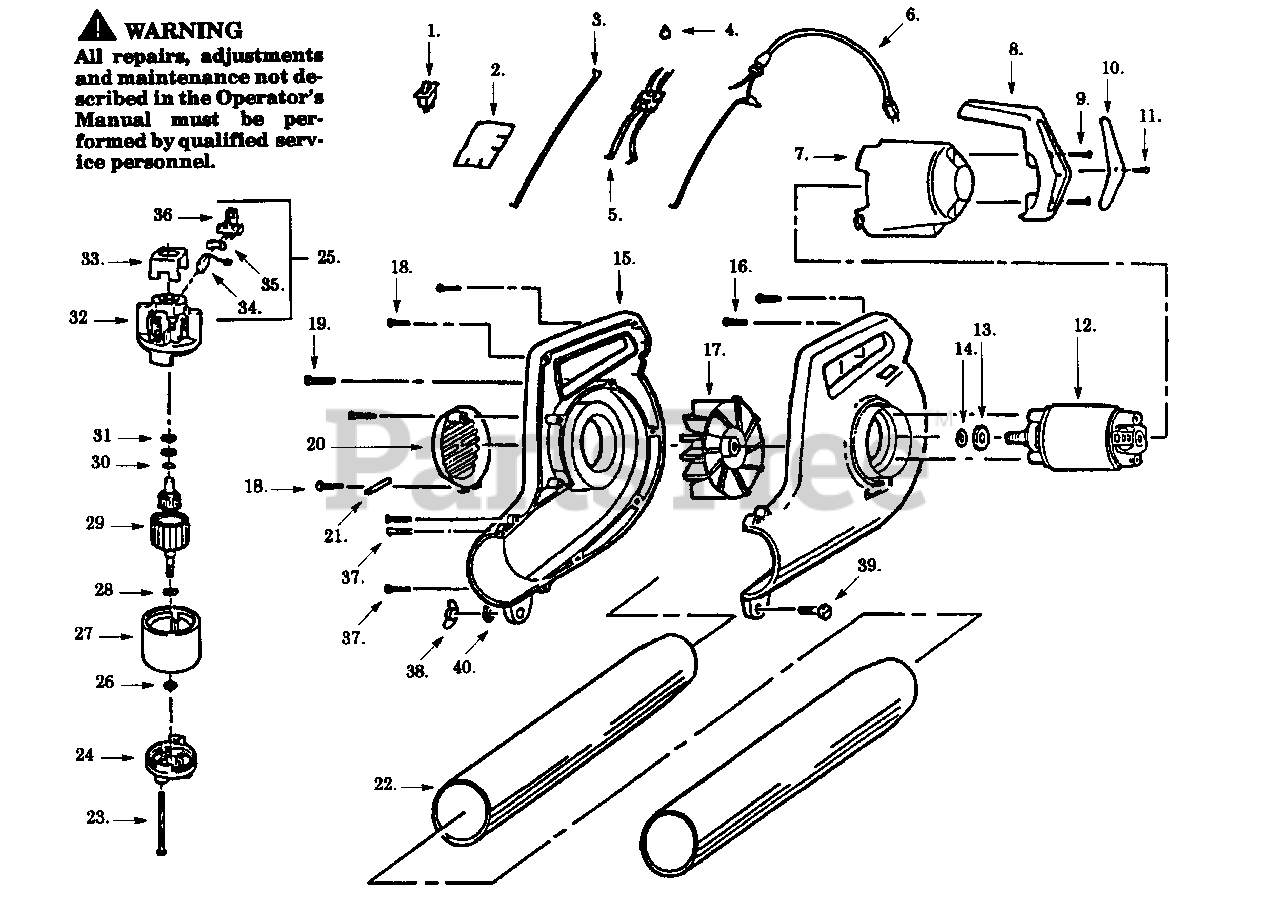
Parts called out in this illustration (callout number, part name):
1	On-Off Switch
2	Mounting Board
3	Lead Wire Ass'y.
4	Connector
5	P.C. Board Ass'y.
6	Power Cord Ass'y.
7	Motor Cover
10	Warning Plate
14	Retainer Ring
15	R.H./L.H. Housing
17	Impeller
20	Inlet Cover
21	Hinge Pin
22	Outlet Tube
24	Endbell Output
25	Brush Kit (Inc. 34,35,36)
27	Field Ass'y.
28	Retainer Ring
29	Armature
30	Retainer Ring
32	Endbell (Brush)
33	Insulator
35	Brush Spring
36	Brush Holder
38	Wing Nut
